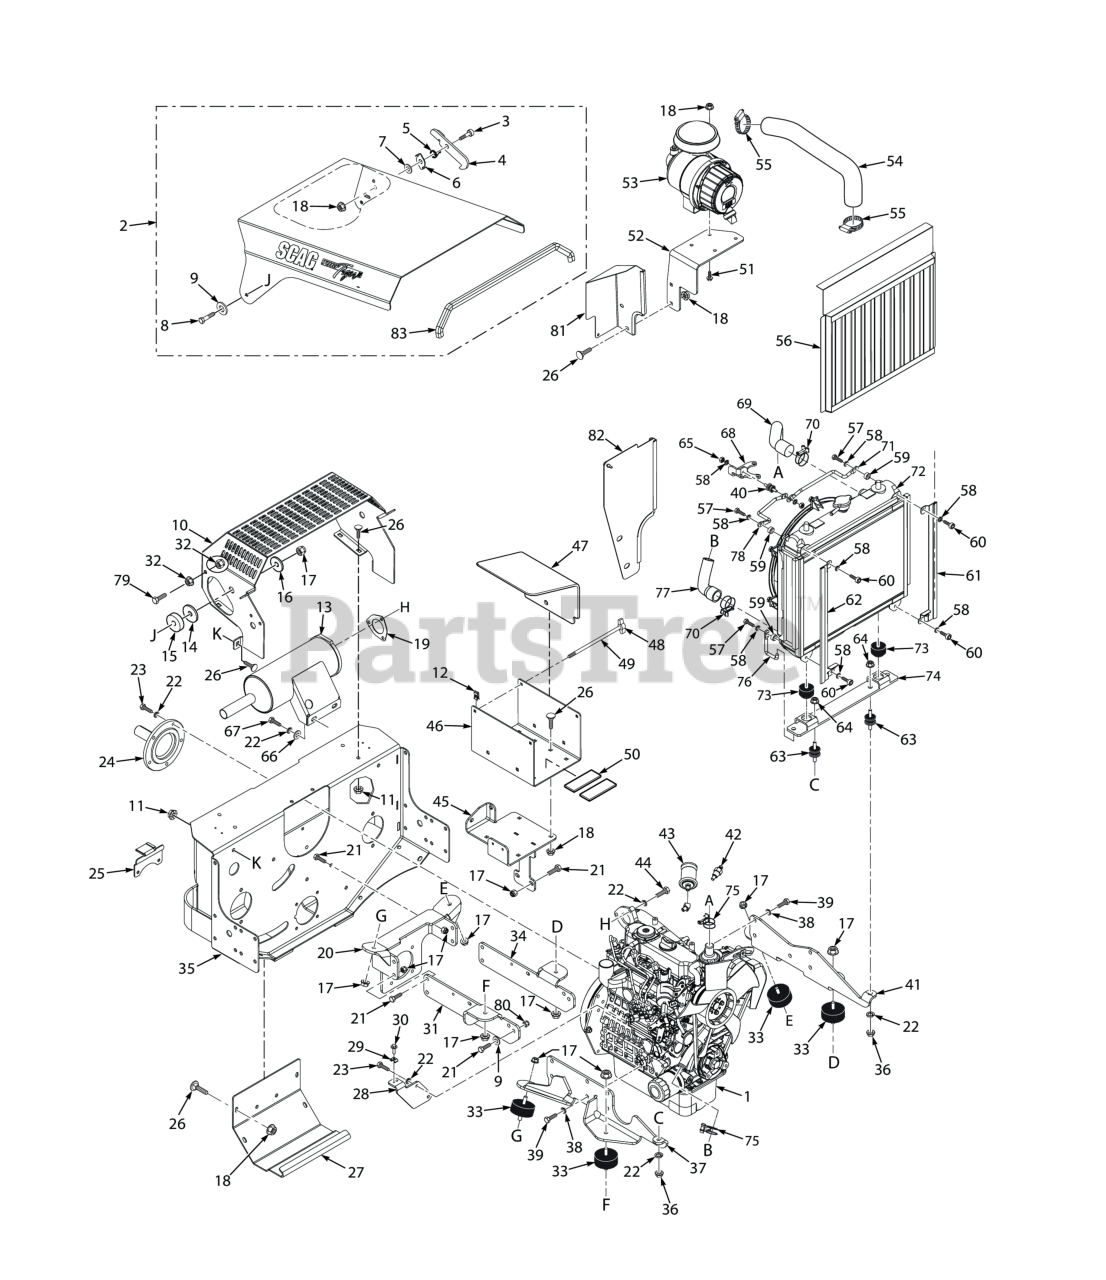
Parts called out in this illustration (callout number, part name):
1	Engine, D902 - Kubota
2	Hood Assy., STTII (Kubota Diesel)
3	Bolt, Shoulder 5/16-18 x 1/2"
4	Latch, Hood
5	Spring, Hood Latch
6	Lock, Hood Latch
7	Flatwasher, 3/8 (.406 x .812 x .065)
8	Bolt, Hex Head 3/8-16 x 1-3/4" (Kohler EFI)
9	Flatwasher, 3/8" Special (.391 x .938 x .105)
10	Guard, Muffler
11	Nut, Flange Head Elastic Stop 5/16-18
12	Bolt, Hex Head 3/8-16 x 1"
13	Muffler, Kubota
14	Disc, Anti-Friction
15	Spacer, Hood
16	Flatwasher, 3/8-.406 x 1-1-1/2 x 7 Gauge
17	HEX NUT, ELASTIC STOP LOCK, 3/8-16
18	Nut, Serrated Flange 5/16-18 (Right Front Engine Mounting, Briggs and Kohler Only)
19	Gasket, Muffler
20	Plate, Rear Engine Mount
21	Bolt, Hex Head, 3/8-16 x 1 Gr. 5
22	Lockwasher, 5/16 (.317 x .586 x .078) Helical Spring
23	Bolt, Metric Hex Head M8-1.25 x 20LG
24	Stub Shaft, (Kubota)
25	Bracket, Belt Guide
26	Bolt, 5/16-18 x .75 RHSN Carriage
27	Cover, Rear
28	Bracket, Control Mount
29	Clamp
30	SCREW, 10-32 X 3/4" SELF TAP
31	Plate, Engine Mount RH
32	NUT, 3/8-16 SERRATED FLANGE HEX HEAD
33	Mount, Engine Isolation
34	Plate, Engine Mount LH
35	Pump Mounting Plate Weldment (Diesel)
36	Nut, Metric Hex M8-1.25mm
37	Mounting Bracket Weldment RH
38	Lockwasher, 7/16� Spring
39	Bolt, Metric Hex Head M10-1.25 x 25LG
40	ISO Mount, Upper Radiator
41	Mounting Bracket Weldment LH
42	Temperature Sensor, Engine Coolant
43	Sender Unit, Oil Pressure
44	Bolt, Metric Hex Head M8-1.25 x 30LG
45	Battery Bracket Weldment (Diesel Only)
46	Battery Box w/Decal (Diesel Only)
47	Cover, Battery (Diesel Only)
48	Knob, 1/4" Wing
49	Bolt, Hex Head 1/4-20 x 8"
50	PAD, BATTERY SUPPORT
51	Cpscrw, 5/16-18 x 1"Serrated Flange Hex Head
52	Bracket, Air Cleaner Mount
53	Air Filter Assembly (Enginaire p/n 67150)
54	Hose, Air Intake
55	Clamp, 2-3/4" Max. Dia.
56	Debris Screen Assembly (With Upper Foam)
57	Bolt, Metric Hex Hd. M6-1.0 x 30mm
58	Lockwasher, 1/4� Spring
59	Spacer, Radiator
60	Capscrew, Metric M6-1.0 x 16mm
61	Debris Screen Track RH
62	Debris Screen Track LH
63	ISO Mount, Lower Radiator
64	Nut, Metric Serr. Flng. M8 x 1.25
65	Nut, Metric Hex M6 x 1
66	Flatwasher, 5/16-.344 x .688 x .065 (48V / 52V)
67	Bolt, Metric Hex Head M8-1.25 x 25LG
79	Bolt, Hex Head 3/8-16 x 1-3/4" (Kohler EFI)
80	Nut, Flange Elastic Stop Nut, 3/8-16
81	Heatshield Assembly, Air Filter
82	Heatshield Assembly, Engine
83	Trim Seal
